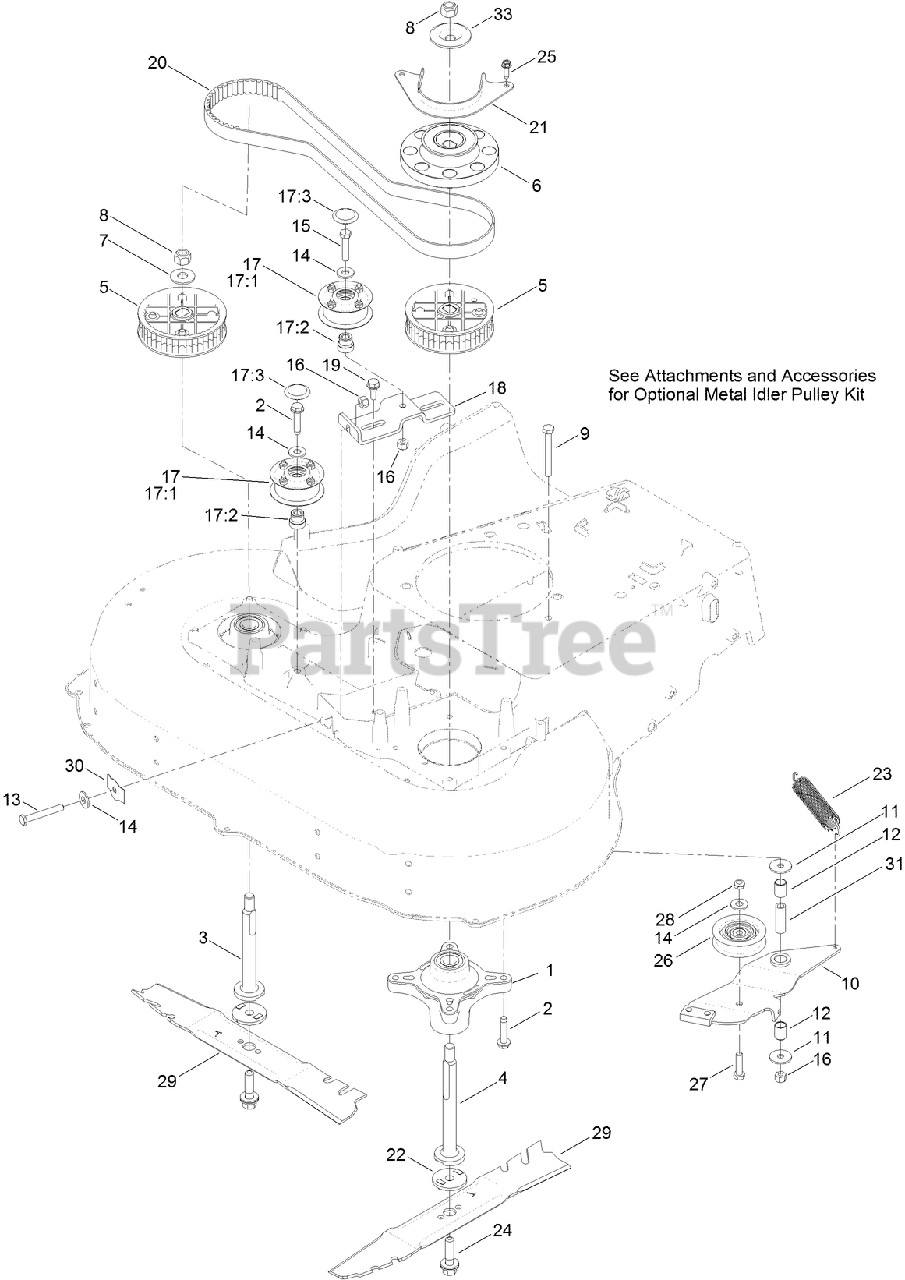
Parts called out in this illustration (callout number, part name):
1	SPINDLE ASM
3	SHAFT-SPINDLE
4	SHAFT-SPINDLE
5	SPROCKET
6	PULLEY-BRAKE, SPINDLE
7	WASHER-SPRING
8	NUT-HEX
9	SCREW-HH
10	BRAKE ARM ASM
11	WASHER-PIVOT
12	Bushing-Sleeve
13	BOLT-TAP, HH
14	WASHER-FLAT
15	SCREW-HH
16	NUT-LOCK, NI
17	PULLEY KIT
17:1	PULLEY ASM
17:2	ADAPTER-BORE
17:3	PLUG-CAP
18	BRACKET-IDLER
19	SCREW-SHOULDER, HHF
20	BELT-SYNCHRONOUS
21	GUIDE-BELT, SPINDLE
22	ADAPTER-BLADE
23	SPRING-EXTENSION, BRAKE
24	BOLT-BLADE
25	SCREW-HWHTF
26	PULLEY-IDLER
27	SCREW-HH
28	NUT-LOCK, NI
29	BLADE-ROTARY
30	SPRING-FLAT
31	Spacer-Brake
33	WASHER-CUP
